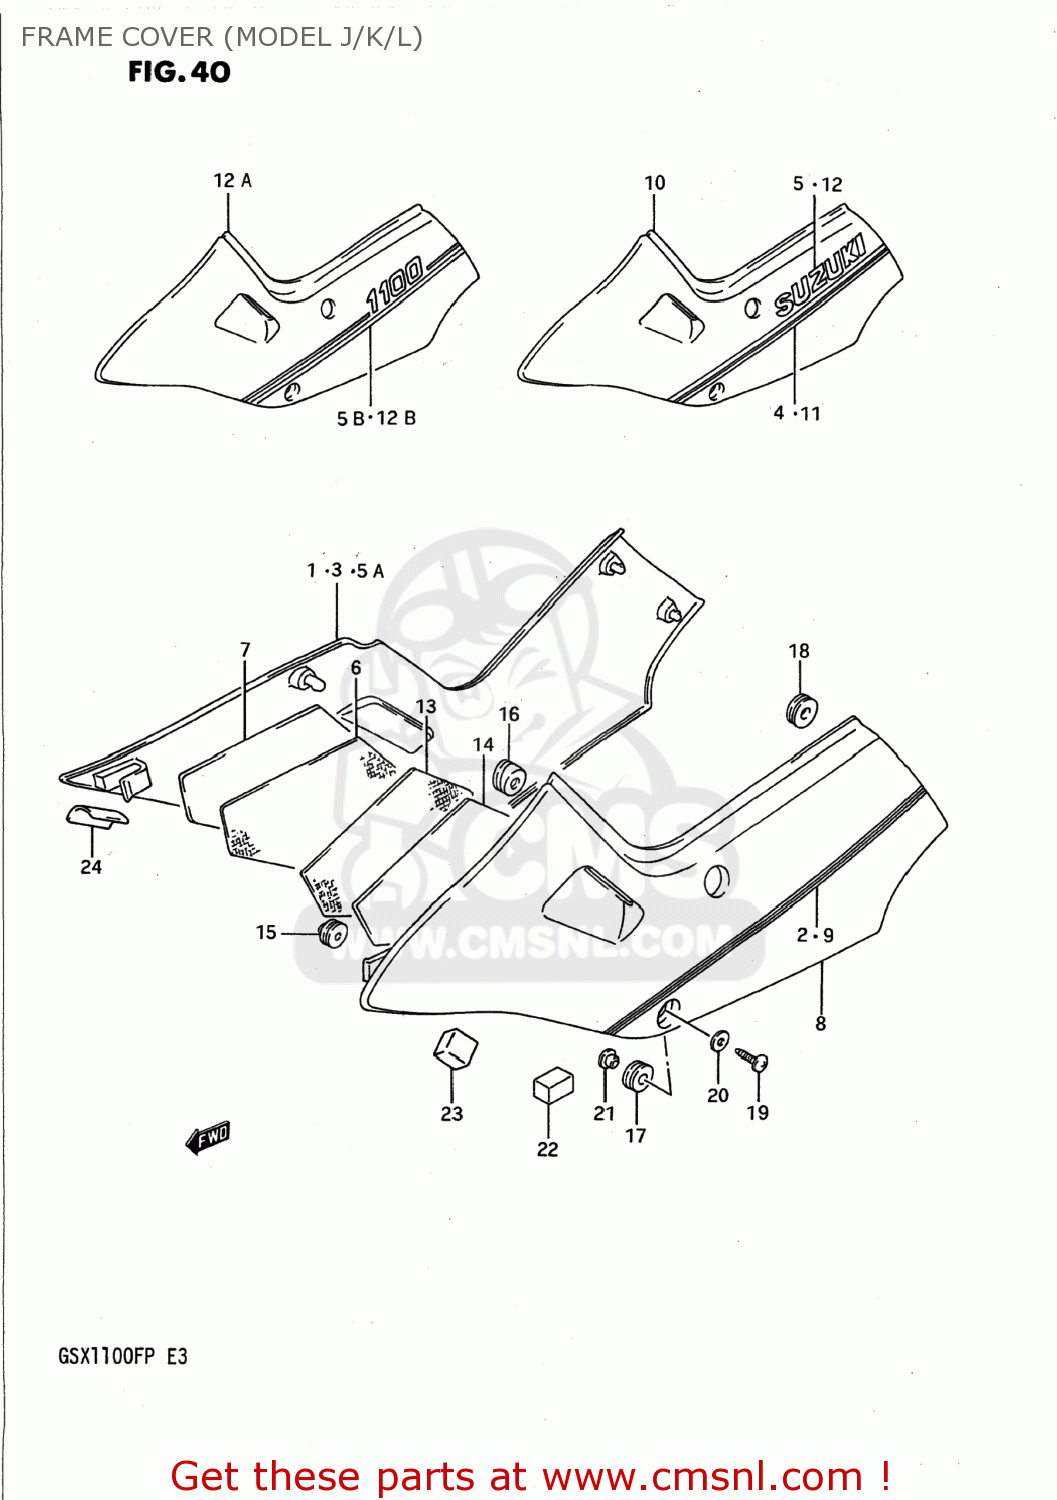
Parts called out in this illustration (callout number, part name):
1	COVER,FRAME,RIGHT
2	TAPE,FRAME COVER,RIGHT
3	COVER,FRAME,RIGHT
4	TAPE,FRAME COVER
5	EMBLEM
5A	COVER COMP,FRAME,RIGHT
5B	TAPE,FRAME COVER,RIGHT
6	HEAT SHIELD,FRAME COVER
7	BALANCER,SEAT FRAME COVER
8	COVER,FRAME,LEFT
9	TAPE,FRAME COVER
10	COVER,FRAME,LEFT
11	TAPE,FRAME COVER
12	EMBLEM
12A	COVER COMP,FRAME,LEFT
12B	TAPE,FRAME COVER,LEFT
13	HEAT SHIELD,FRAME COVER
14	BALANCER SHEET,FRAME C
15	CUSHION,COVER FRAME FR NO.1
16	CUSHION,COVER FRAME FR NO.2
17	CUSHION,SEAT TAIL COVER SIDE
18	CUSHION
19	SCREW(6X27)
20	WASHER(6.5X18X1.6)
21	WASHER
22	CUSHION,FRAME COVER
23	CUSHION
24	PROTECTOR,FRAME COVER FR
